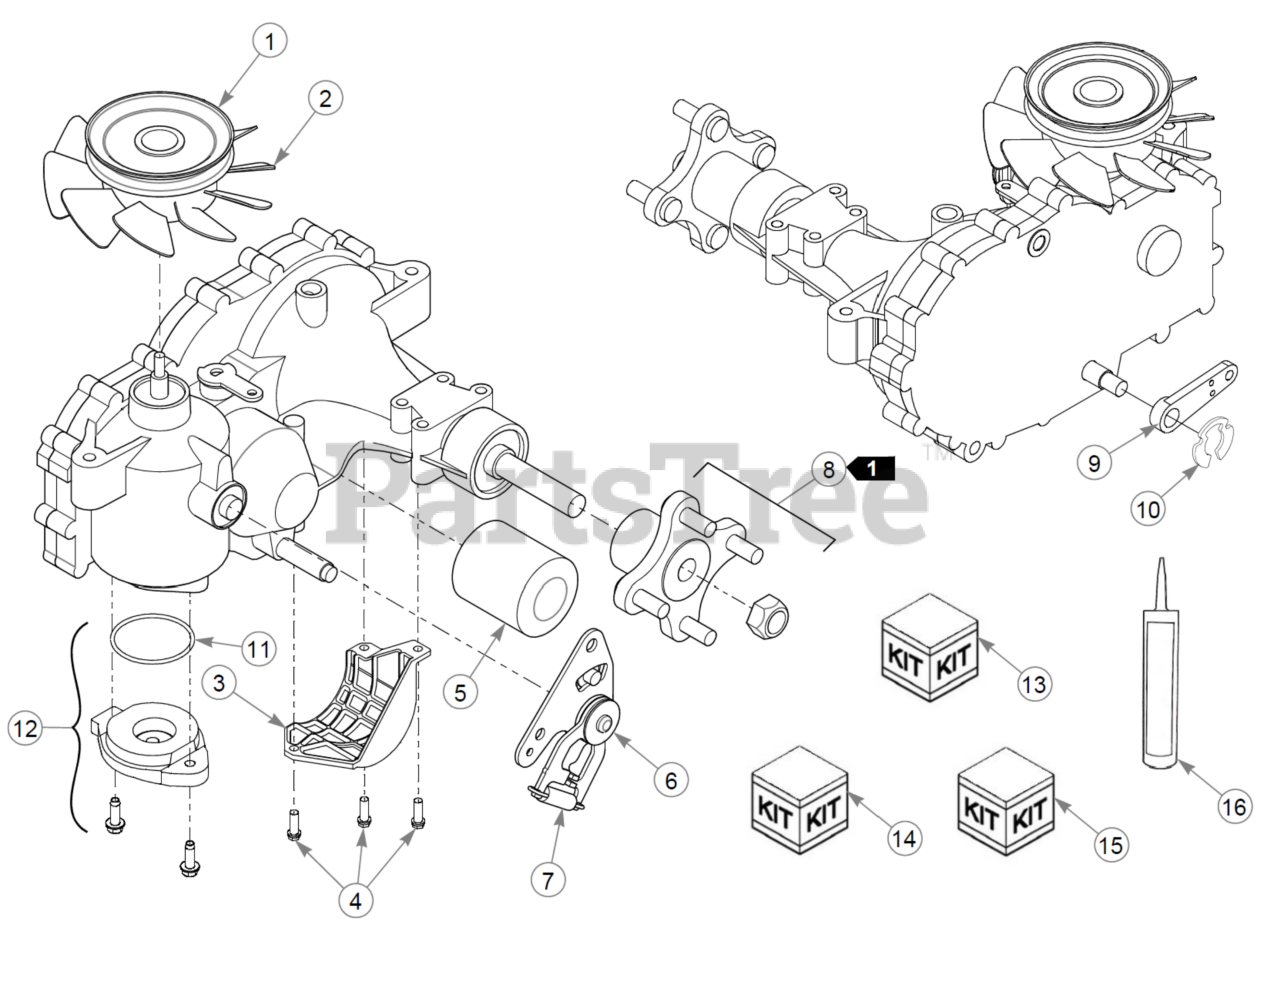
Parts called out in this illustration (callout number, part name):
1	FAN / PULLEY KIT
2	FAN - 7.0" (10 BLADE)
3	GUARD, TRANS FILTER
4	CS .250-20 X .75 HX FLG
5	HYDRAULIC OIL FILTER
6	HG RTN CW
7	HG RTN SPRING
8	KIT, HUB, 4 BOLT
9	ZT2800 BRAKE ARM - 2007
10	CLIP, RETAINING
11	O-RING, ZT28/3100 CHARGE
12	COVER, ZT3100 CHRG PUMP
13	OIL RETENSION KIT
14	SEAL KIT
15	KIT - SIDE COVER
16	TUBE - SEALANT
